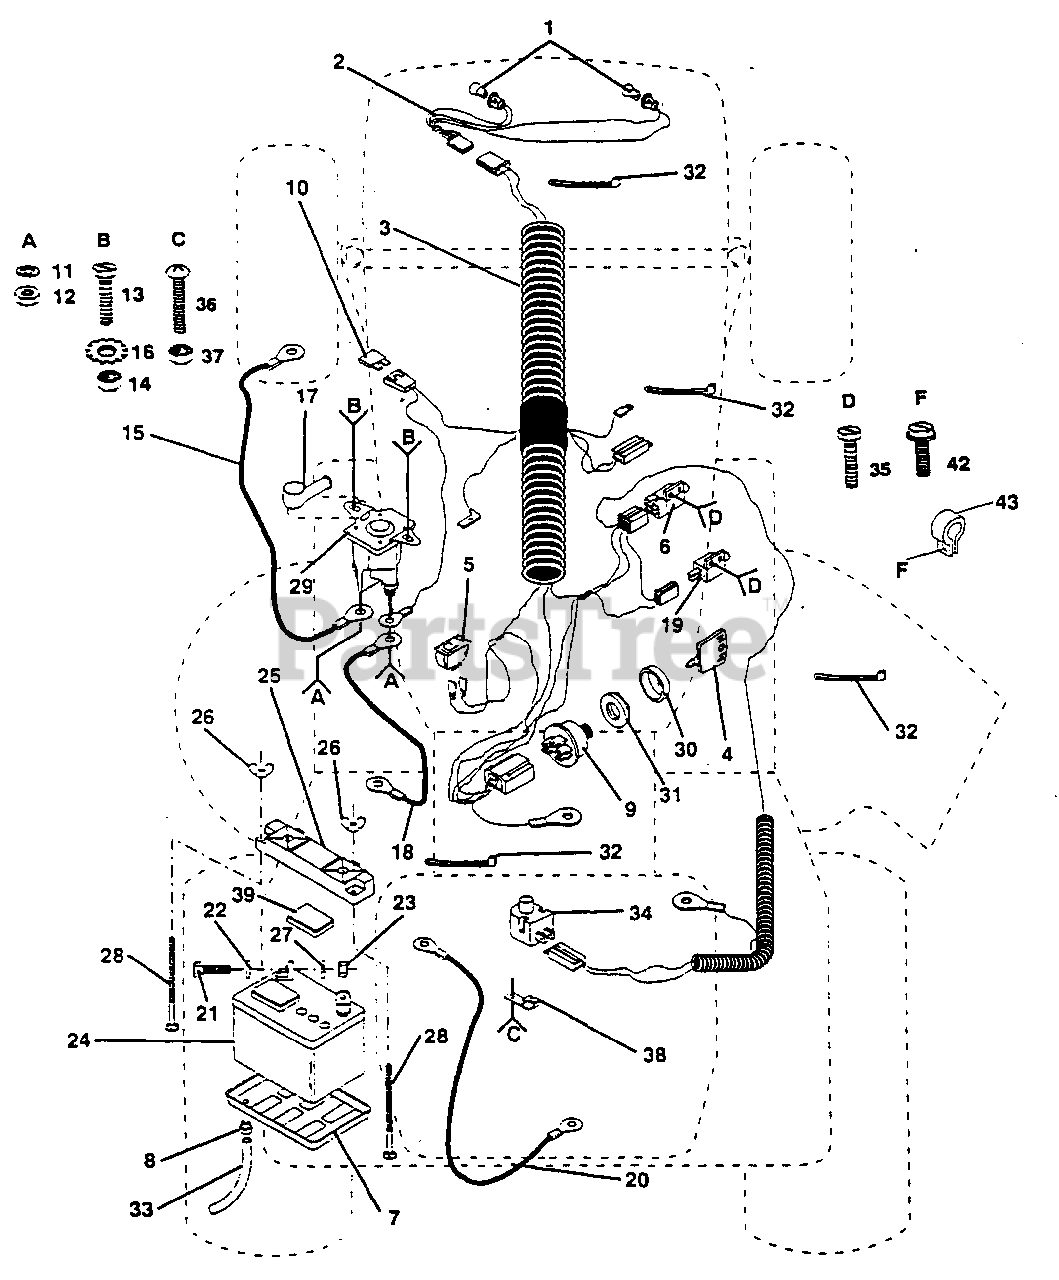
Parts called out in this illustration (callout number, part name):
1	Bulb, Light
2	Harness, Light Socket (AYP part number)
3	Harness, Ignition
4	Key, Molded
5	Switch, Light
6	Switch, Interlock
7	Tray, Battery
8	Clamp, Hose
9	Switch, Ignition (AYP part number)
10	Fuse
11	Washer, Lock 1/4 (AYP part number)
12	Nut, Hex Jam 1/4 - 20
13	Bolt, Hex 1/4 - 20 x 1/2 Grade 5
14	Nut, Keps 1/4 - 20
15	Cable Assembly
16	Washer, Lock, Ext. Tooth 1/4
17	Cover, Terminal
18	Cable, Battery
19	Switch, Interlock
20	Cable, Battery (AYP part number)
21	Bolt, Hex 1/4 - 20 x 3/4
22	Washer 9/32 - 5/8 x 16 Gauge
23	Nut, Hex 1/4 - 20
24	Battery (AYP part number)
25	Guard, Terminal (AYP part number)
26	Nut, Wing 1/4 - 20 (AYP part number)
27	Washer, Lock, Heavy Helical Spring
28	Bolt, Carriage 1/4 - 20 x 7-1/2
29	Solenoid (AYP part number)
30	Bezel, Ignition (AYP part number)
31	Nut, Ignition (AYP part number)
32	Cable Tie
33	Tube, Battery Tray (AYP part number)
34	Switch, Seat
35	Screw, Hex Tapping #10 - 24 UNC x 1/2
36	Screw, Slotted Pan Head #10 - 32 x 1/2 (AYP part number)
37	Nut, Keps #10 - 32 x 1/2
38	Clip, Insulated
39	Caps, Battery
42	Screw, Hex Washer Head, Thread Rolling 3/8 x 16 x 1/2
43	Clip, Insulated
